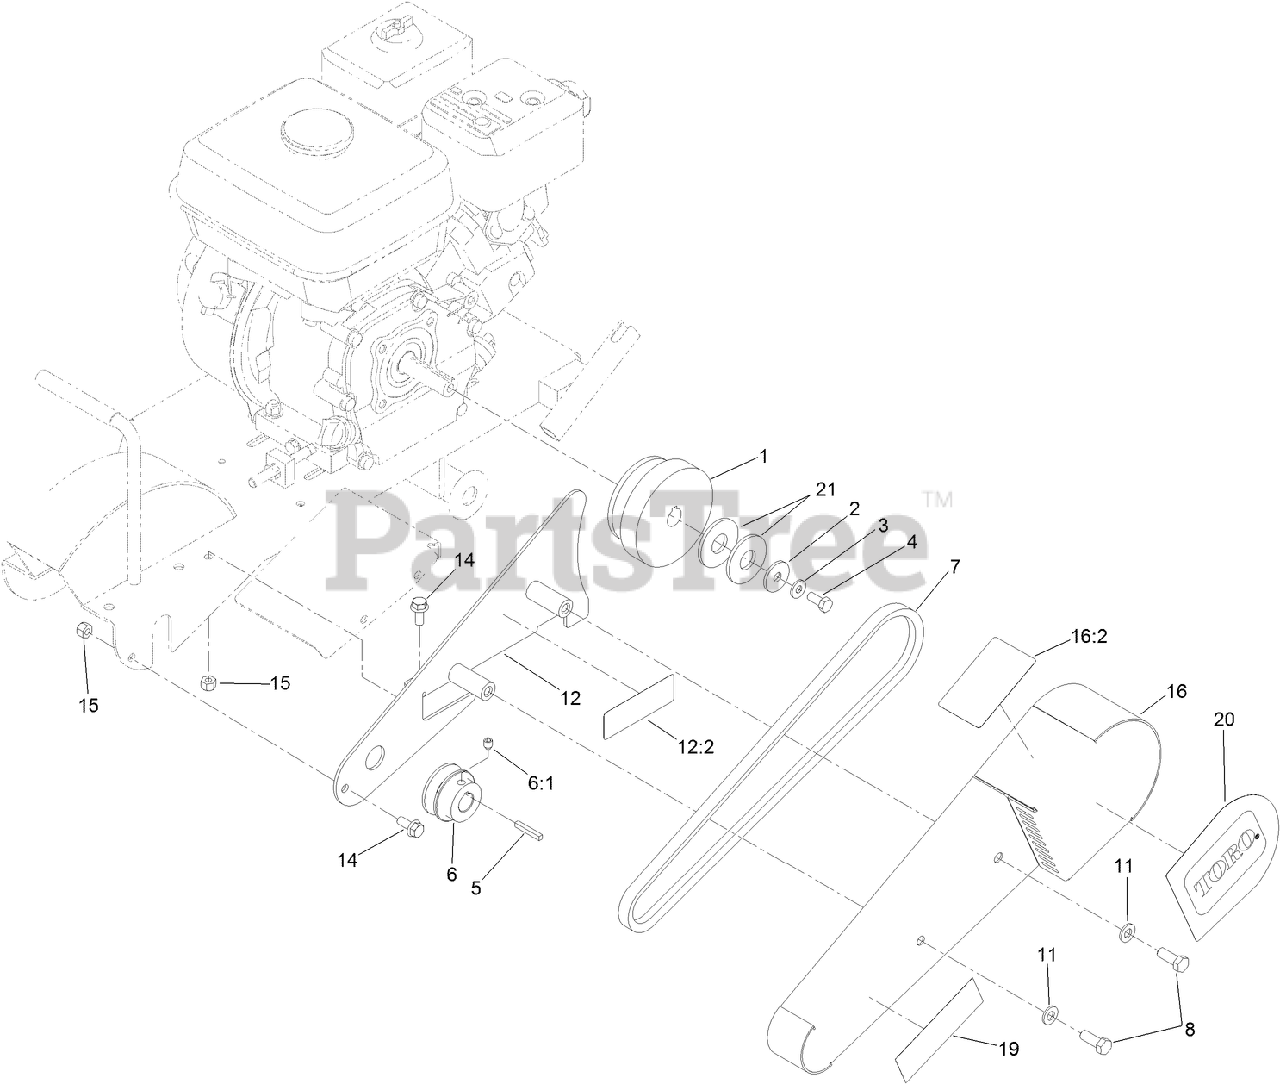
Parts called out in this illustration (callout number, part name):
1	CLUTCH-CENTRIFUGAL
2	WASHER
3	WASHER-FLAT
4	SCREW-HH
5	KEY-SQUARE
6	PULLEY-FRONT
6:1	SCREW-HSH
7	BELT-DRIVE
8	SCREW-HH
11	WASHER-FLAT
12	PLATE-GUARD, INNER
12:2	DECAL-WARNING, SHIELDS
14	SCREW-HHF
15	NUT-LOCK, NI
16	BELT GUARD ASM
16:2	DECAL-CAUTION
21	WASHER-FLAT
